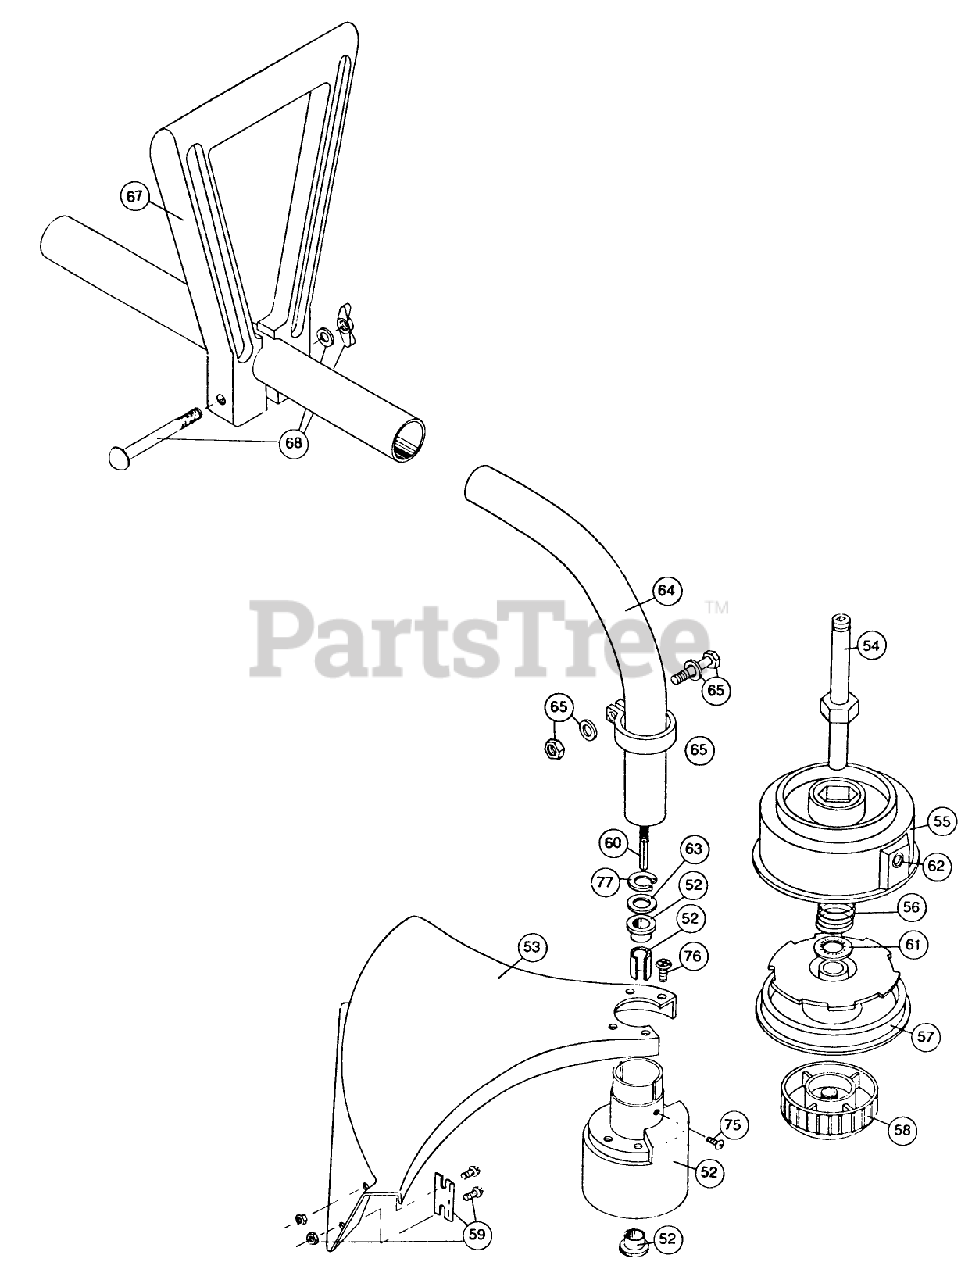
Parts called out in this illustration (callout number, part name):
52	BUSHING HSG ASM
57	REEL - INNER
59	BLADE ASM
61	RETAINER WASHER
75	ANTI-ROTATION SCREW
76	GUARD MOUNTING SCREW
77	RETAINING RING
